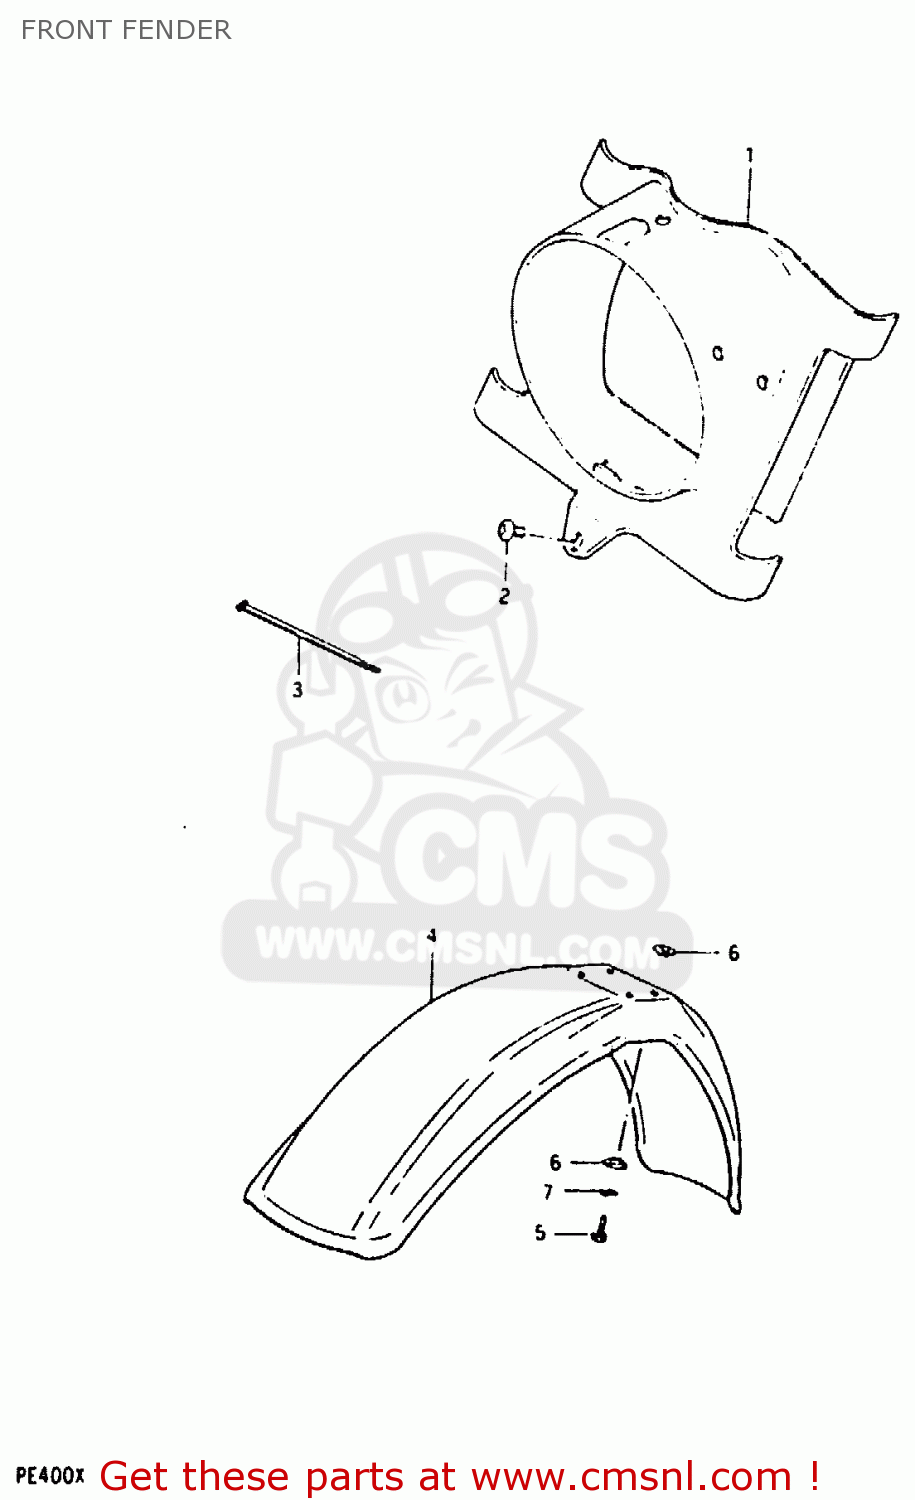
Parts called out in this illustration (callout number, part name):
1	HOUSING,HEADLAMP
2	SCREW
3	CLAMP
4	FENDER,FRONT
5	BOLT, UPPER
6	WASHER
7	LOCK WASHER
